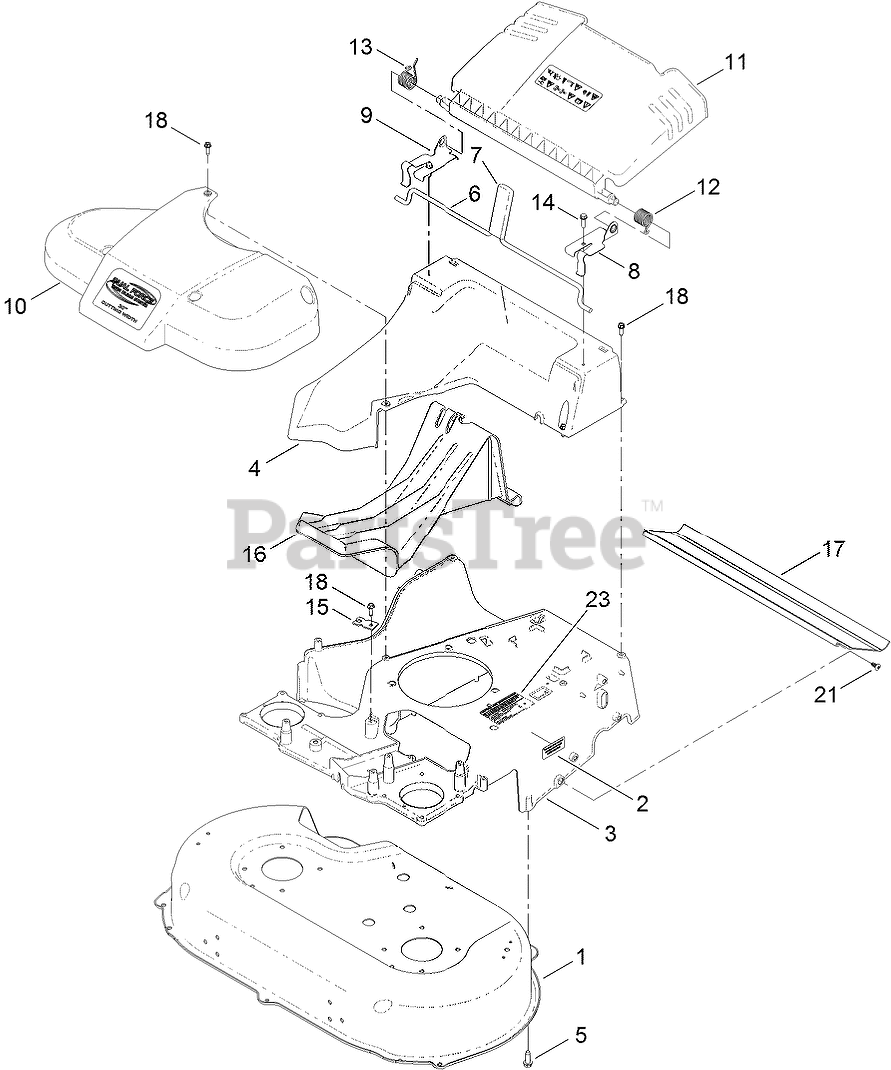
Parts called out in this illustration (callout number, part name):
1	HOUSING ASM
2	DECAL-LOCATION, SERVICE DEALER
4	CHUTE
5	SCREW-HWHTF
6	ROD-RELEASE, HANDLE
7	GRIP-LEVER
8	BRACKET-DOOR, LH
9	BRACKET-DOOR, RH
10	BELT COVER ASM
11	REAR DEFLECTOR ASM
12	SPRING-TORSION
13	SPRING-TORSION
14	SCREW-HWH
15	BRACKET-CABLE, TRACTION
16	PLUG-MULCH
17	SHIELD-TRAILING
18	SCREW-HWHTF
21	SCREW-PTH
23	DECAL-ARRESTER, SPARK
